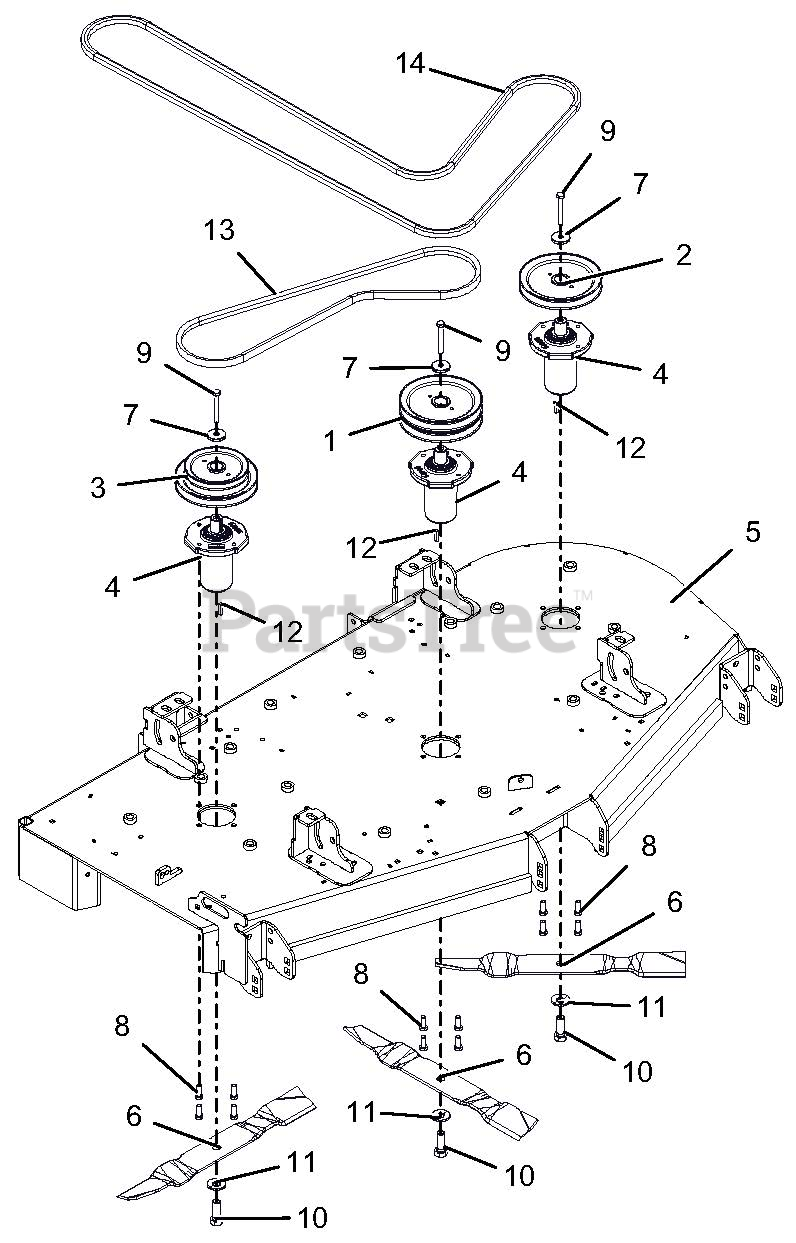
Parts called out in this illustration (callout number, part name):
1	PULLEY, DOUBLE-1"ID X 6.75"OD
2	PULLEY, V-1" ID X 6.75" OD
3	PULLEY, DBL-1"IDX6.75"&5.25"OD
4	ASM, MAINT FREE SPINDLE
5	WLDMT, 60" SIDE DISCH DECK
6	BLADE, MULCH (60")
7	RETAINER, SHEAVE
8	BLT-HEX .38-16X1.0 GR8 YZ EP30
9	BLT-HEX .38-16X2.75 GR8 YWZC
10	BLT-HEX .62-18X1.75 GR8 YWZC
11	WSHR-BLVL .669X1.535X.138
12	KEY, SQ .25X.25X1.00 RC 40-50
13	V-BELT, B-COGGED
14	HEX BELT, BB-WRAPPED
